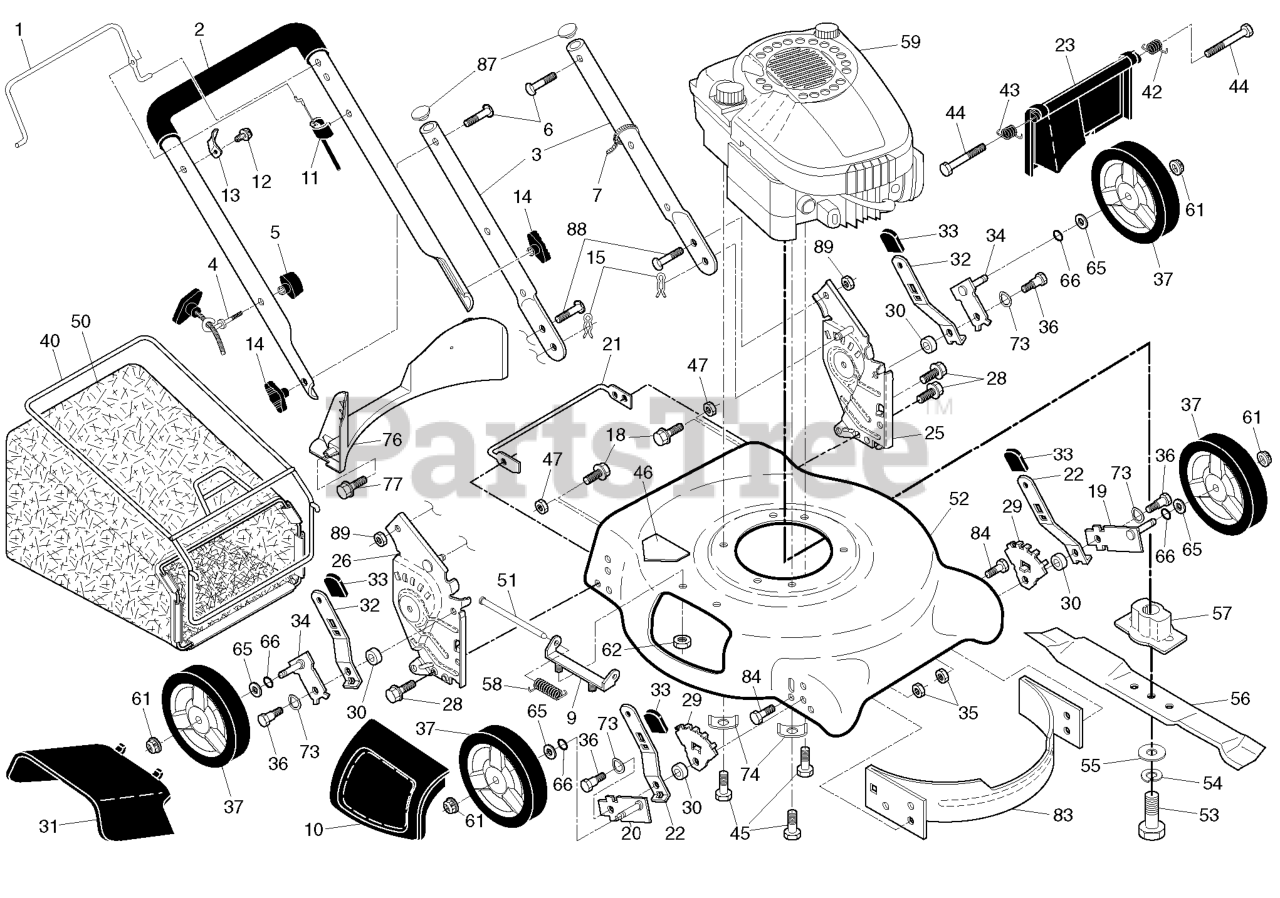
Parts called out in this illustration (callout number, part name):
1	CONTROL BAR
2	HANDLE.UP.ASM.DST.ECON.498.GRP
3	HANDLE.LOWER.DOME.BT.GREY
4	GUIDE.ROPE.BLK.ZINC.CHROM
5	T-KNOB.NEW ROPE GUIDE
6	BOLT, HANDLE 5/16-18X1.75
7	TIE GUIDE
9	BRACKET.ASM.HOUSING.EZ.MUL
10	DOOR.MULCH.21".REAR.PUSH.GRAY
11	CABLE.MZR.22.2012
13	BRACKET.UPSTOP.RT
14	KNOB, DEFLECTOR
15	HAIRPIN COTTER
18	SCREW 1/4X20
19	AXLE ARM ASSY FRONT LH
20	AXLE ARM ASSY FRONT RH
21	FOOT.GUARD.21.DOM/FGD.CE.10
22	SELECTOR SPRING, FRONT
23	DOOR.REAR.21.DOMED.498
25	BRACKET.ASM.HAND.LW.21.LT.GREY
26	BRACKET.ASM.HAND.LW.21.RT.GREY
28	SCREW 14-20 X 5/8
29	WHEEL ADJ BRACKET FRONT
30	SPACER.HEIGHT.ADJUSTER
31	DEFLECTOR.CLIPPING.21.GREY
32	SPRING.SELECTOR.21RD.HTTRT.BZP
34	ARM.ASM.AXLE.REAR.5/9.POS.BZP
35	NUT.FLANGE.HEX.5/16X18.BLACK
36	SHOULDER BOLT 5/16-18
37	WHEEL & TIRES ASSY, FRONT
40	FRAME.BAG.21.REAR.DOMED.PUSH
42	SPRING.LH.22.REAR.DOOR.EZ.EMPT
43	SPRING.RH.22.REAR.DOOR.EZ.
45	BOLT 3/8-16X1-1/8
46	DECAL.INTERNATIONL.CUTFINGER
47	NUT.71038.31-18.HEX.NYLOCK
50	GBAG.2323029ER.HU.VENT.GRY.SIL
51	ROD.HINGE.COMBI-C
52	HOUSING.21MC.DOME.ORANGE.CE
53	SCREW, HEX HD 3/8-24 X 1-3/8
54	LOCKWASHER
55	WASHER,HARDEN
56	BLADE.21.PUSH
57	ADAPTER.BLADE.W/KEY.25MM.CE
58	TORSION SPRING
61	NUT.HEX.FLANGE.3/8-16.LO(3 2)
62	LOCKNUT.NYLOC.1/4-20
65	WASHER.FLAT.1/2
66	O-RING..070X.487.NEOPRENE
73	WASHER.CURVED.CYLINDRICAL
74	WASHER.ENGINE.BZP
76	BAFFLE.REAR.PLASTIC.21.RD.ECON
77	SCREW.HX.13X.750
83	BAFFLE.FRONT.21.DOME.US
84	BOLT.5/16HEX.WHS.HD
87	PLUG.PLASTIC.7/8".14-20.GAUGE
88	BOLT.CARRIAGE.LN.5/16-18X.5/8
89	LOCKNUT-FLANGE 5/16-18
